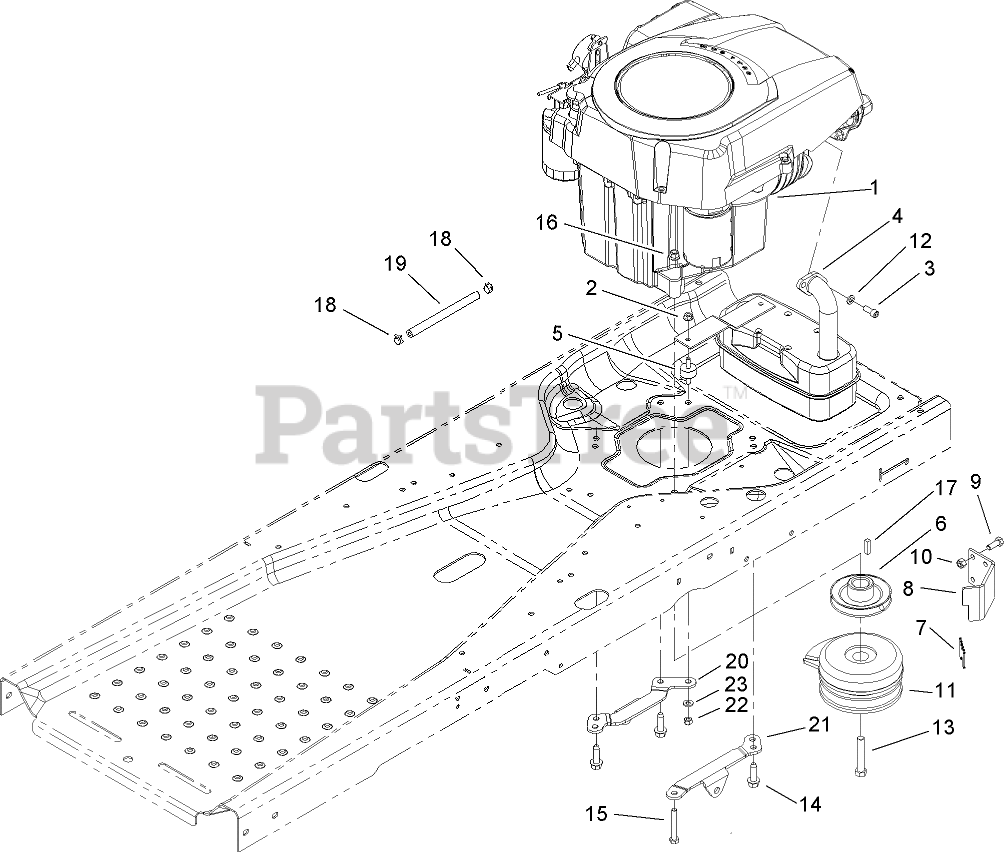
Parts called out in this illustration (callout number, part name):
2	NUT-HF
3	SCREW-HSH
4	MUFFLER-KOHLER
5	ISOLATOR
6	PULLEY-ENGINE
7	BUMPER
8	STOP-CLUTCH
9	SCREW-HH
10	NUT-LOCK, NI
11	CLUTCH-ELECTRIC, PTO
12	WASHER-LOCK
13	SCREW-HH
14	SCREW-TAPTITE
15	SCREW-HH
16	NUT-LOCK, NI
18	CLAMP-HOSE
19	HOSE-FUEL
20	SUPPORT-HYDRO, RH
21	SUPPORT-HYDRO, LH
22	NUT-LOCK, NI
23	WASHER-FLAT
